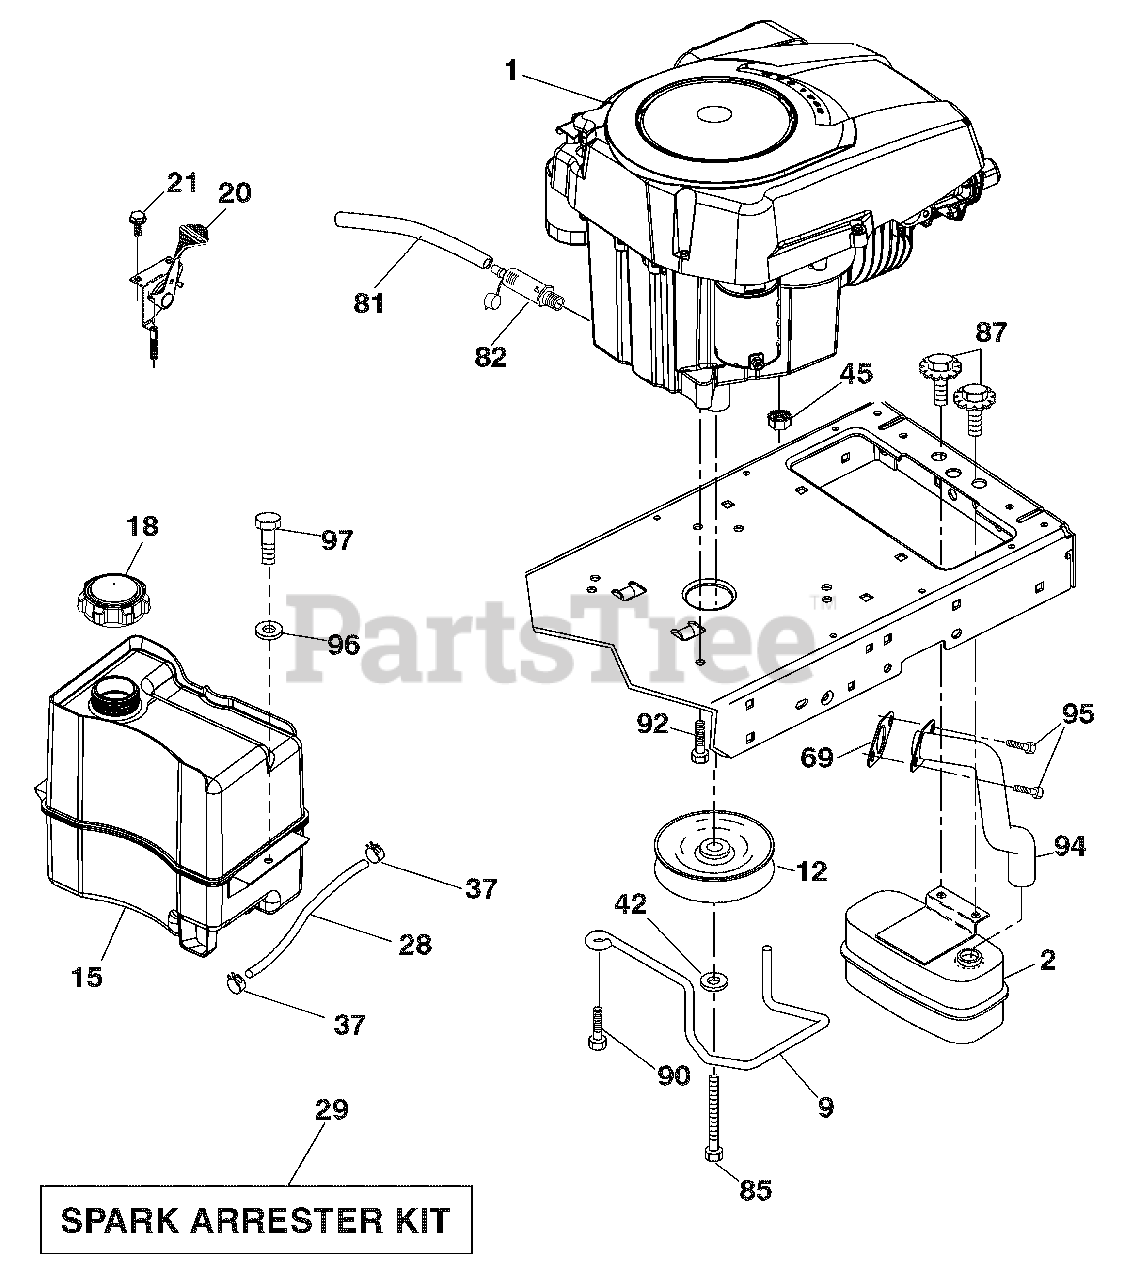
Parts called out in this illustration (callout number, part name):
9	Keeper Belt Engine
12	Pulley Engine
15	Tank Fuel
18	Cap Asm
20	Control Throttle
21	Screw 10 x 3/4 Single Lead Hex
28	Fuel Line
29	Spark Arrester Kit
37	Clamp Hose
42	Washer Lock 7/16
45	Nut Keps Hex 1/4-20 unc
81	Tube Drain Oil Easy
82	Plug Drain Oil
85	Bolt Hex 7/16-20 x 4 x Gr. 5-1.5 Thr
87	Bolt 5/16-18 UNC x 3/4 w/Sems
90	Screw 3/8-16 x 1
92	Screw 3/8-16 x 1
94	Tube Exhaust
95	Screw Socket Hd. 5/16-18 x .75
96	Washer 9/32 x 7/8 x 16 Ga.
97	Screw 1/4-20 x 3/4
